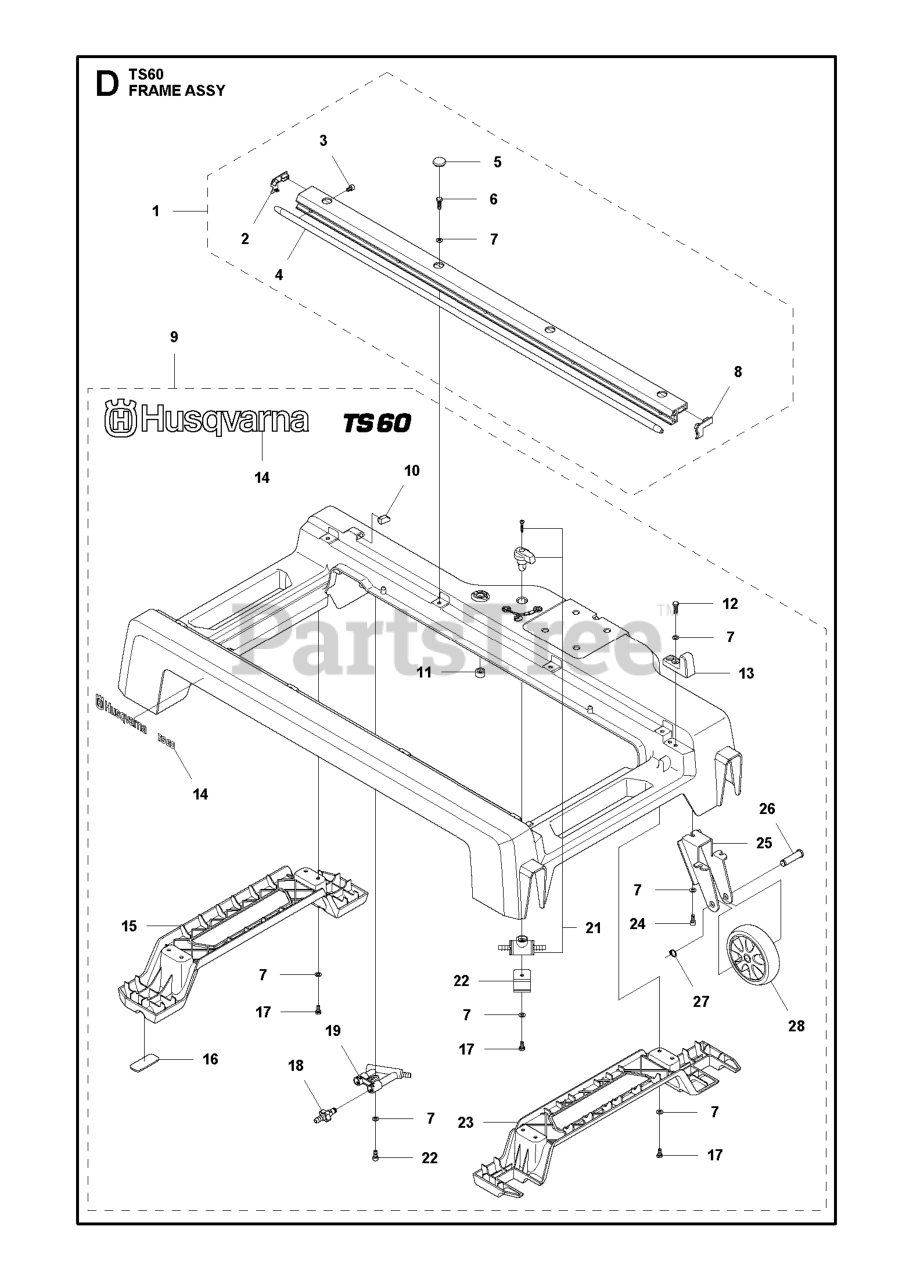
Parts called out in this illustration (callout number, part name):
7	WASHER
20	SCREW
27	Snap Ring, 24r
